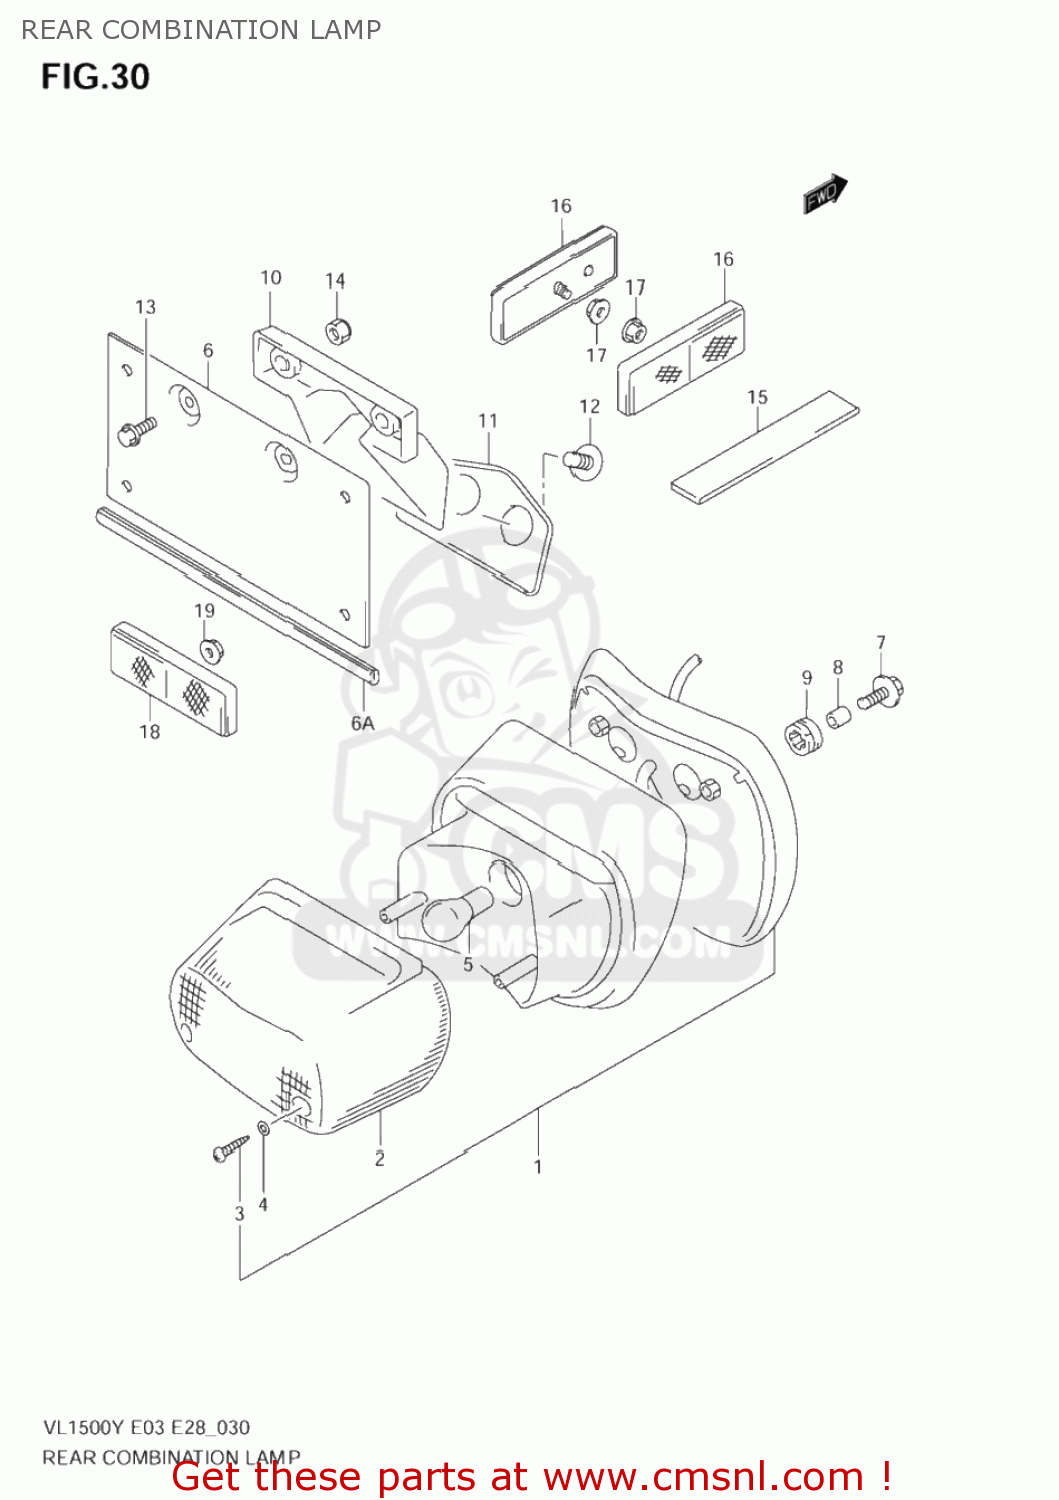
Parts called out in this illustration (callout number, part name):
1	LAMP ASSY,RR COMBINATION
2	LENS
3	SCREW
4	GASKET (NAS)
5	BULB(12V21/5W)
6	HOLDER,LICENSE PLATE
6A	MOLDING
7	BOLT(6X20)
8	SPACER(6.5X10X10)
9	CUSHION
10	STAY,LICENSE PLATE HOLDER
11	CUSHION,LICENSE PLATE HOLDER
12	BOLT(6X16)
13	SCREW(6X16)
14	NUT
15	PROTECTOR(20X90)X1.0
16	REFLEX REFLECTOR ASSY,RR
17	NUT
18	REFLECTOR ASSEMBLY,REAR
19	NUT
